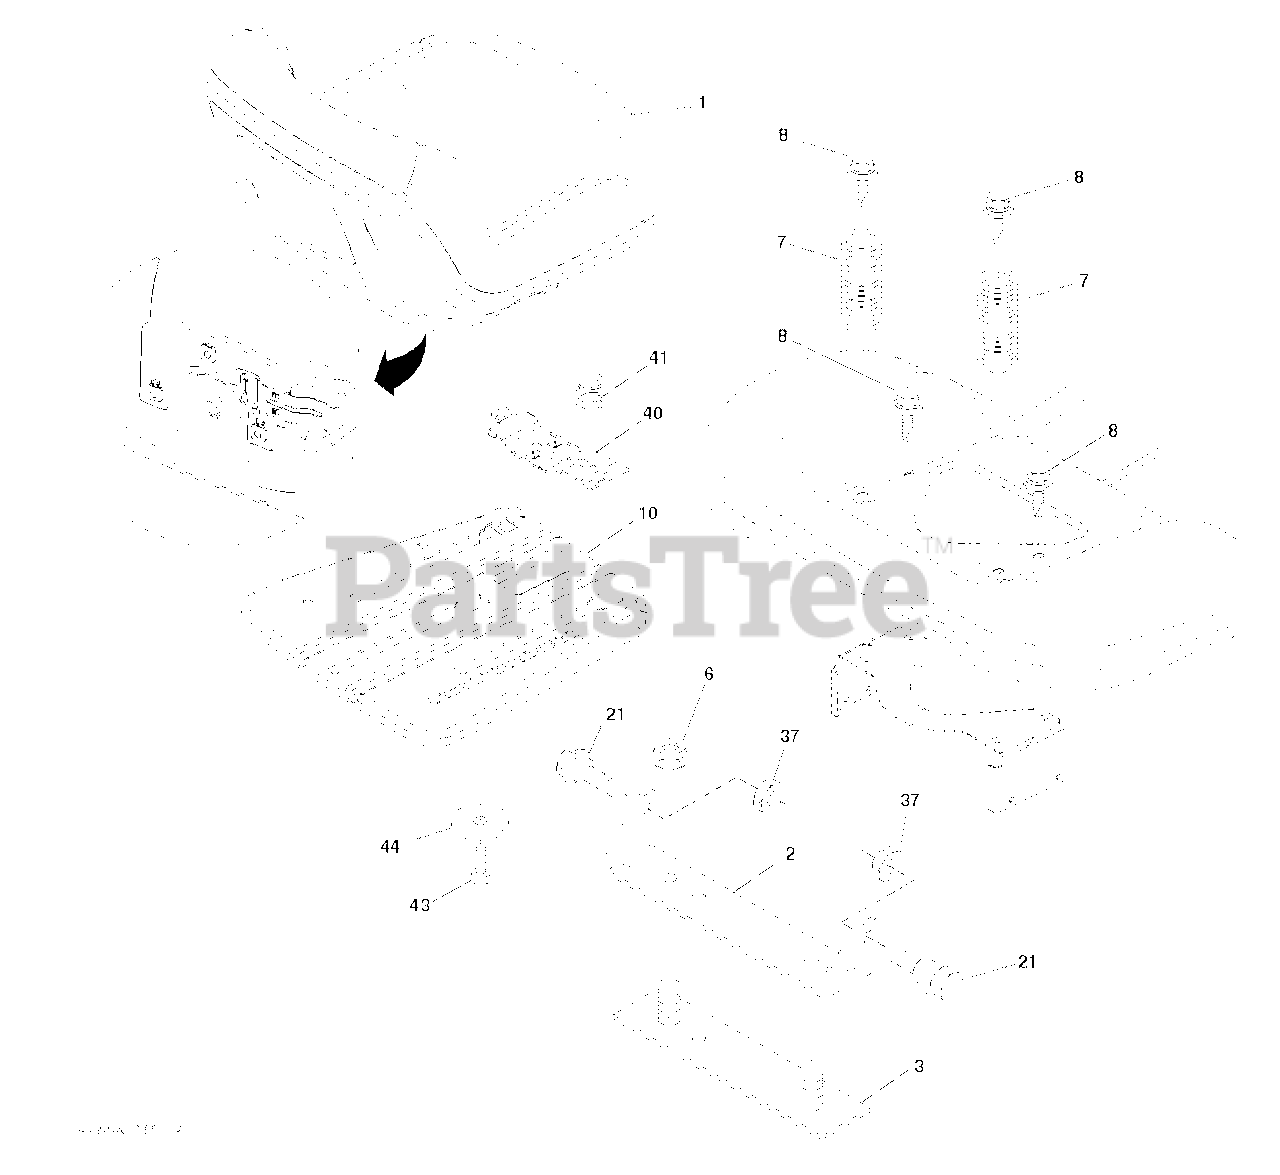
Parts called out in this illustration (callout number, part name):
1	SEAT.TG150.BLK.NLOGO.
2	BRKT.PIVOT.FENDER
6	NUT
7	Compression Spring, Seat Black
8	BOLT, 5/16-18 X 1 3/4
10	PAN.ASM.SEAT.3PT
21	Shoulder Bolt, 5/16-18 X 5/8
37	NUT.71038.31-18.HEX.NYLOCK
40	HANDLE.SLIDE.SEAT.TEX.BLACK
41	SPRING.LATCH.SEAT.TEX
44	WASHER 13/32 X 2-3/8 X 12GA
